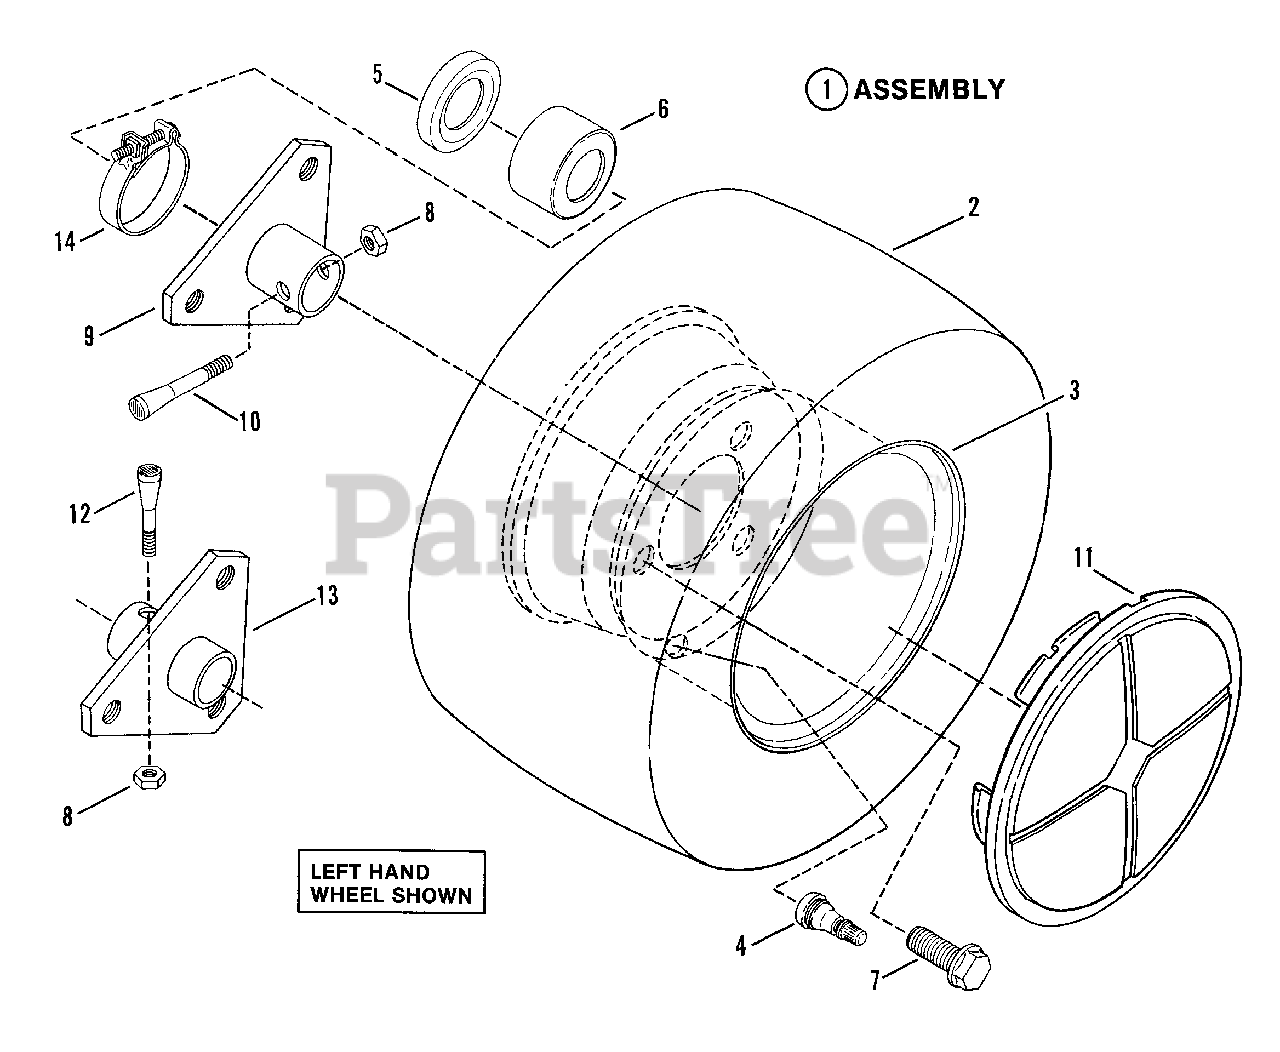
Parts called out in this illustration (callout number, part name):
1	ASSEMBLY, Rear Tire & Rim
2	TIRE, 18-8.50 x 8
3	RIM, 8 x 7
4	VALVE, Air
5	SEAL, Oil
6	CAP, Seal,
7	BOLT, 1/2-20 x 3/4" Lug
8	NUT, 5/16-24, Lock
9	HUB, Rear Wheel, Left Hand 1.126" ID
10	BOLT, 5/16-24 x 2", Tapered, Left Hand
11	WHEEL COVER
12	BOLT, 5/16-24 x 1-5/8", Tapered, Right Hand
13	HUB, Rear Wheel, Right Hand .75" ID
14	CLAMP
